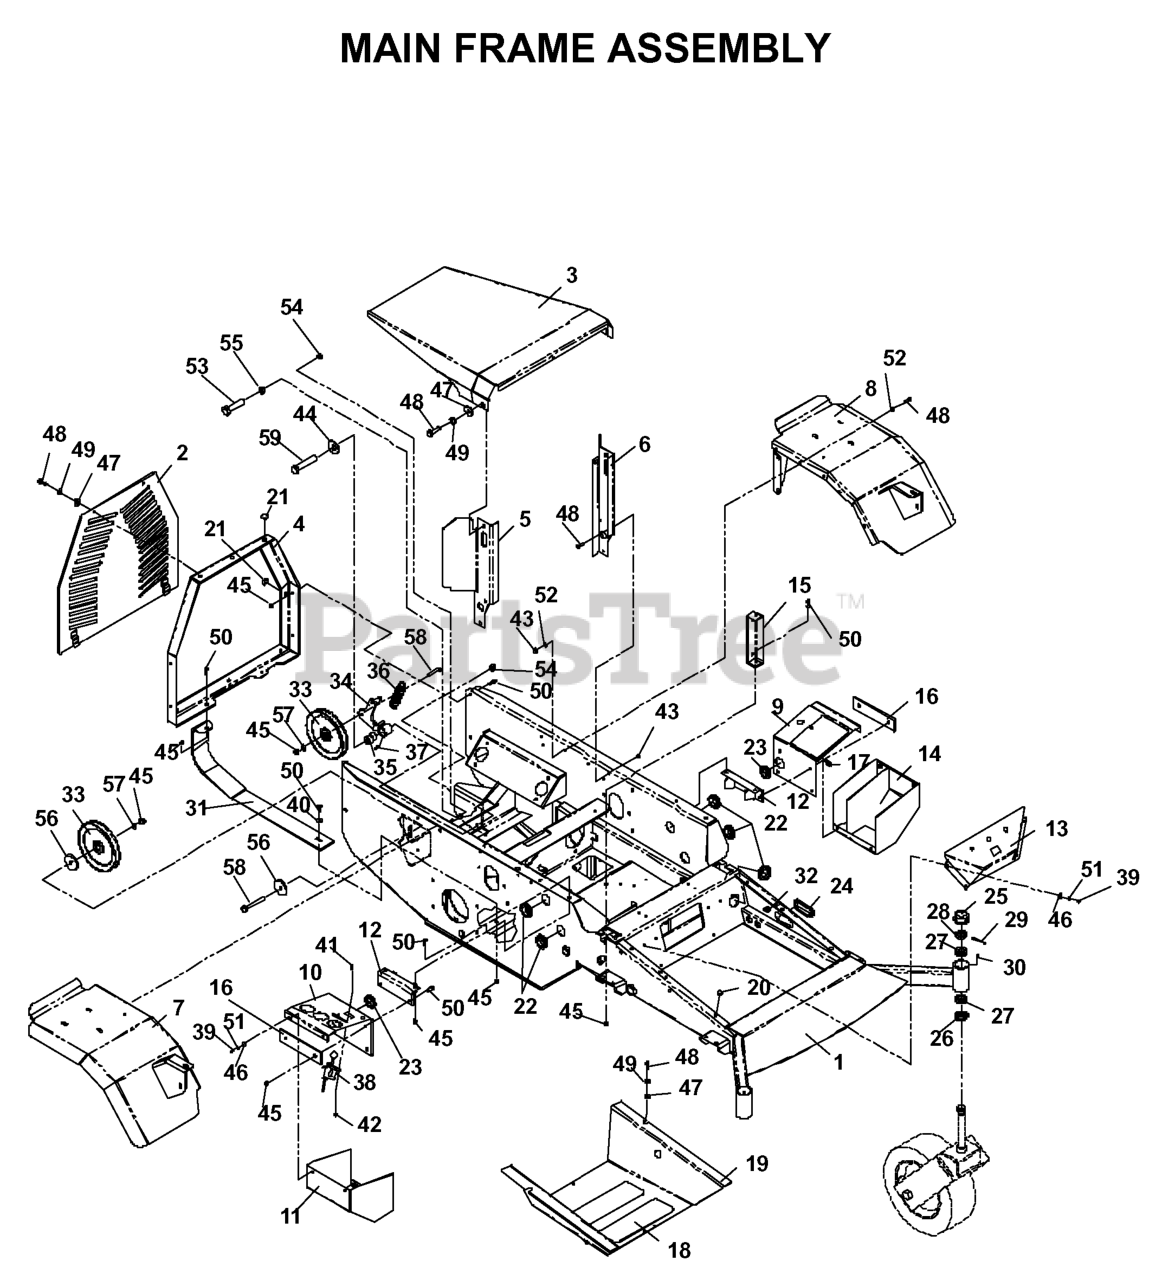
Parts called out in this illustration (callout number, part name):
1	FRAME W/DECALS
2	PANEL W/ DECALS
3	HOOD ORANGE
4	REAR FRAME
5	SUPPORT WLDMT, RT
6	SUPPORT WLDMT, LT
7	FENDER WELDMT, RH
8	FENDER WELDMT, LH
10	CONSOLE TOP-PAINTED
11	CONSOLE BOTTOM
12	MTG ANGLE WELDMT
13	CENTER CONSOLE WELDMENT
14	BOTTOM CONSOLE
15	SUPPORT WELDMENT
16	BLACK-STIFFNER-PAINTED
17	MAGNETIC LATCH
18	ANTI-SKID PAD
19	FOOT PLATE WIDMT
20	GROMMET, BUMPER
21	GROMMET BUMPER
25	GREASE CAP
27	TAPERED ROLLER BRG
28	NUT 1"C HEX SLOTTED
29	COTTER PIN 1/8 X 2
31	SKID PLATE
32	U-CLIP 5/16-18 NUT RETAINER
33	IDLER PULLEY
34	ARM WELDMENT
37	ZERK
38	THROTTLE CONTROL W/BALL KNOB
39	SCREW 1/4 X 5/8
40	WASHER 3/8 FLAT
41	HCS #10-24 X 1/2
42	NUT 10-24 NYLOC
43	NUT 5/16 NYLOC
44	WASHER 1/2 FLAT
45	NUT 3/8-16 NYLOC
46	WASHER 1/4 FLAT
47	WASHER 5/16 FLAT
48	HCS 5/16C X 1
49	WASHER.LOCK.HVY.HLCL.SPR.5/16
50	HCS 3/8-16X1.GRD.5.ZD
51	LOCKWASHER 1/4"
52	FLAT WASHER 5/16 SAE
53	HCS 1/2-13X2 GR 8
54	NUT 1/2-13 HEX NYLOC ZD
55	NUT HEX 1/2
56	SPINDLE WASHER
57	WASHER 3/8 SAE FLAT
58	HCS 3/8C X 2 1/4
59	HEX SCREW 1/2-13 X 2.5" GR 5
